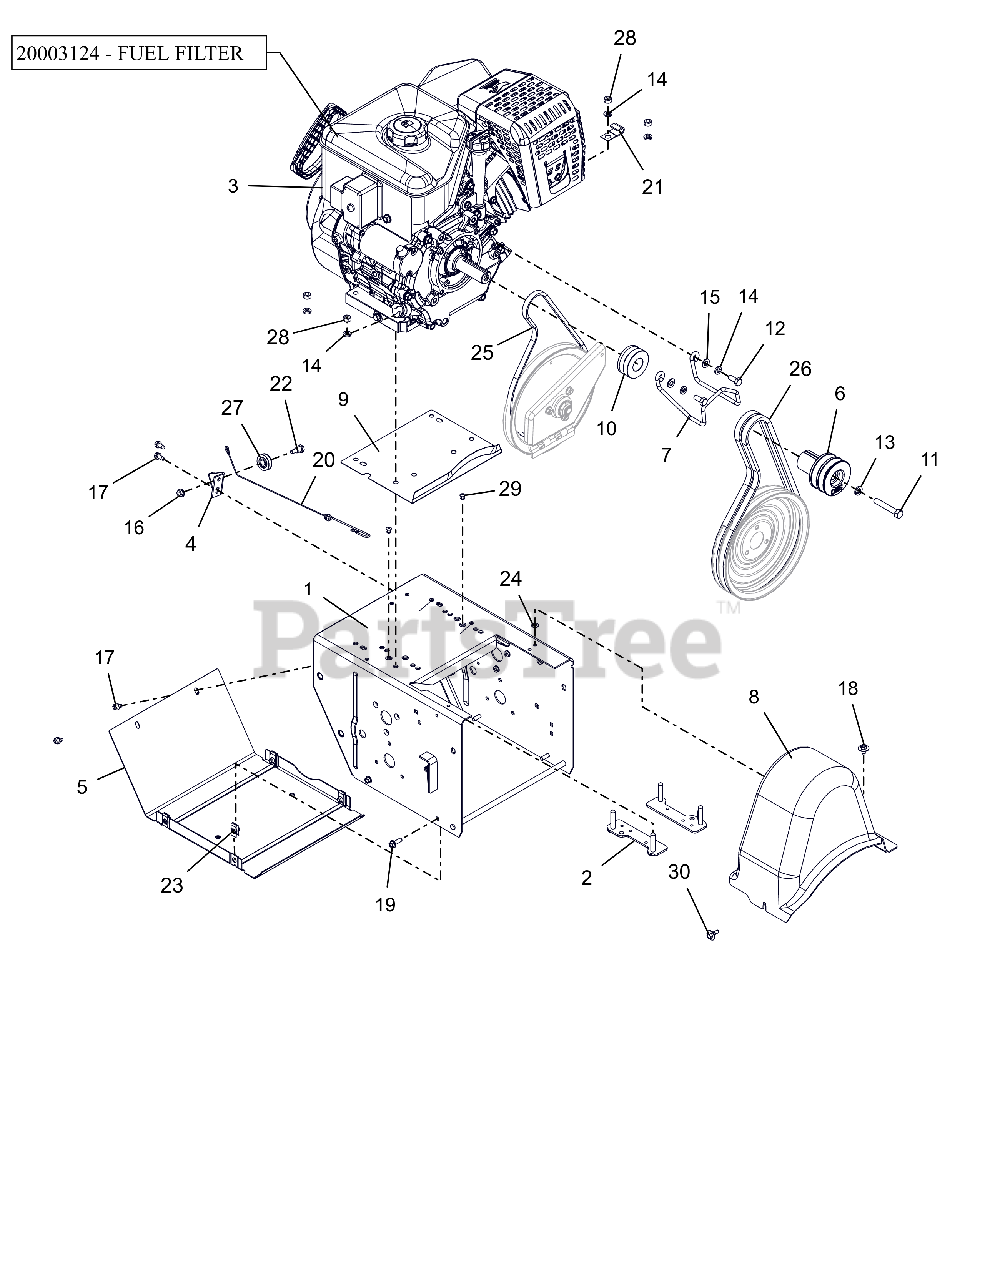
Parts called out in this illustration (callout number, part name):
1	FRAME, MAIN-DELUXE(WELDMENT)
2	STRAP, BOLT-LARGE
3	ENGINE,EFI369 GEN3 120V/60W
4	BRACKET, CABLE PULLEY
5	COVER, BOTTOM
6	SHEAVE,ATTACHMENT-SHO 2 GRV
7	FINGER, BELT
8	COVER, BELT-LARGE
9	BAFFLE, WATER - LARGE BLOCK
10	SHEAVE, TRACTION (KEYLESS)
11	BLT, HEX .38-24X2.25 G5 ZCC
12	BLT, HEX .31-24X.750 G5 ZCC
13	WSHR,LK-REG .375X.094 ZCC
14	WSHR, LK-HVY .312X.097 ZCC
15	WSHR,FLT .344X.688X.065 ZCC
16	NUT-LK-TOP-FLG .250-20 GF ZCC
17	SCR-TAP .25-20X.50 HWH ZCC
18	SCR, TAP .25-20X.50 LG HWH ZCC
19	BLT, HWH .25-20X.75 G5 ZCC
20	CABLE, LOWER TRACTION,SS & PRO
21	J-CLAMP
22	BOLT, SHLDR -.375 X .375 X .25-20
23	NUT-RTNR .25-20X.56
24	NUT-PUSH .25X.50 O.D.
25	V-BELT, 3L-WRAPPED
26	V-BELT, HA-RAW EDGE (SET)
27	PULLEY, CABLE
28	NUT, HEX .312-18 ZCC
29	RVT, POP .1875 ZCC
30	SCR-TAP .25-20X.5 CAPTIVE
